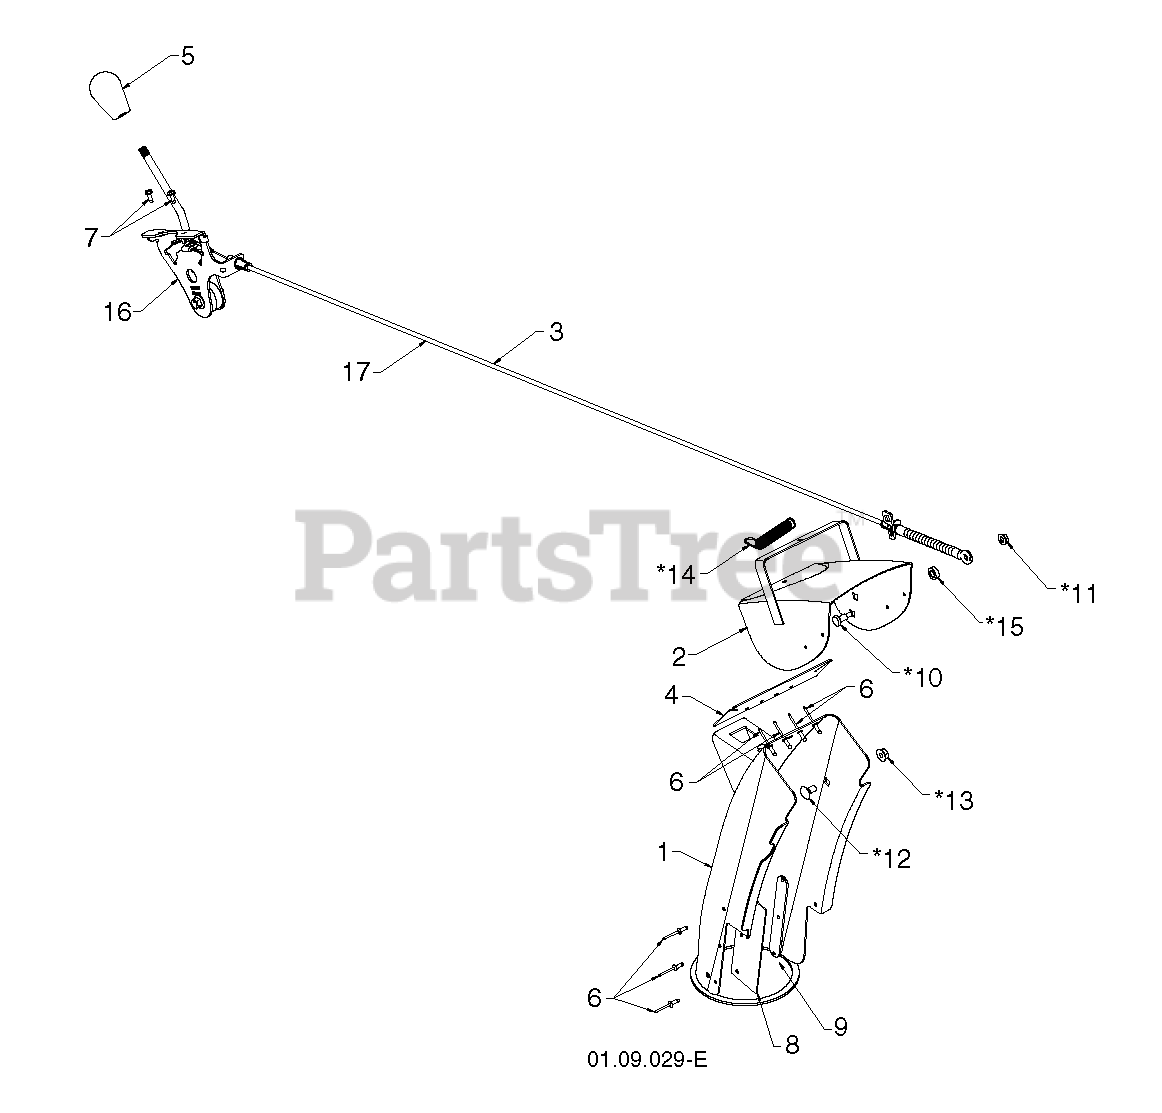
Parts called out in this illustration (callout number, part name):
1	ASM.CHUTE/DEFLECTOR.668
3	CONTROL.ASM.DEFLEC.BLK.BOWDEN
5	KNOB.OVERMOLD.DS.HUSQVARNA/BLK
10	BOLT.CARR.W.3125 SHLDR..25-20
11	NUT.HEX.FLANGE.1/4
12	BOLT CAR BLK 5/16-18 X 5/8
13	LOCKNUT-FLANGE 5/16-18
14	SPRING.DEFLECTOR.REM.CHUTE
15	WASHER.NYLON.326 X.625 X.205
16	RP CNTRL.HEAD.ASSEM.DEFLECTOR
17	RP CABLE.DEFLECTOR.CONTRL.BOWD
